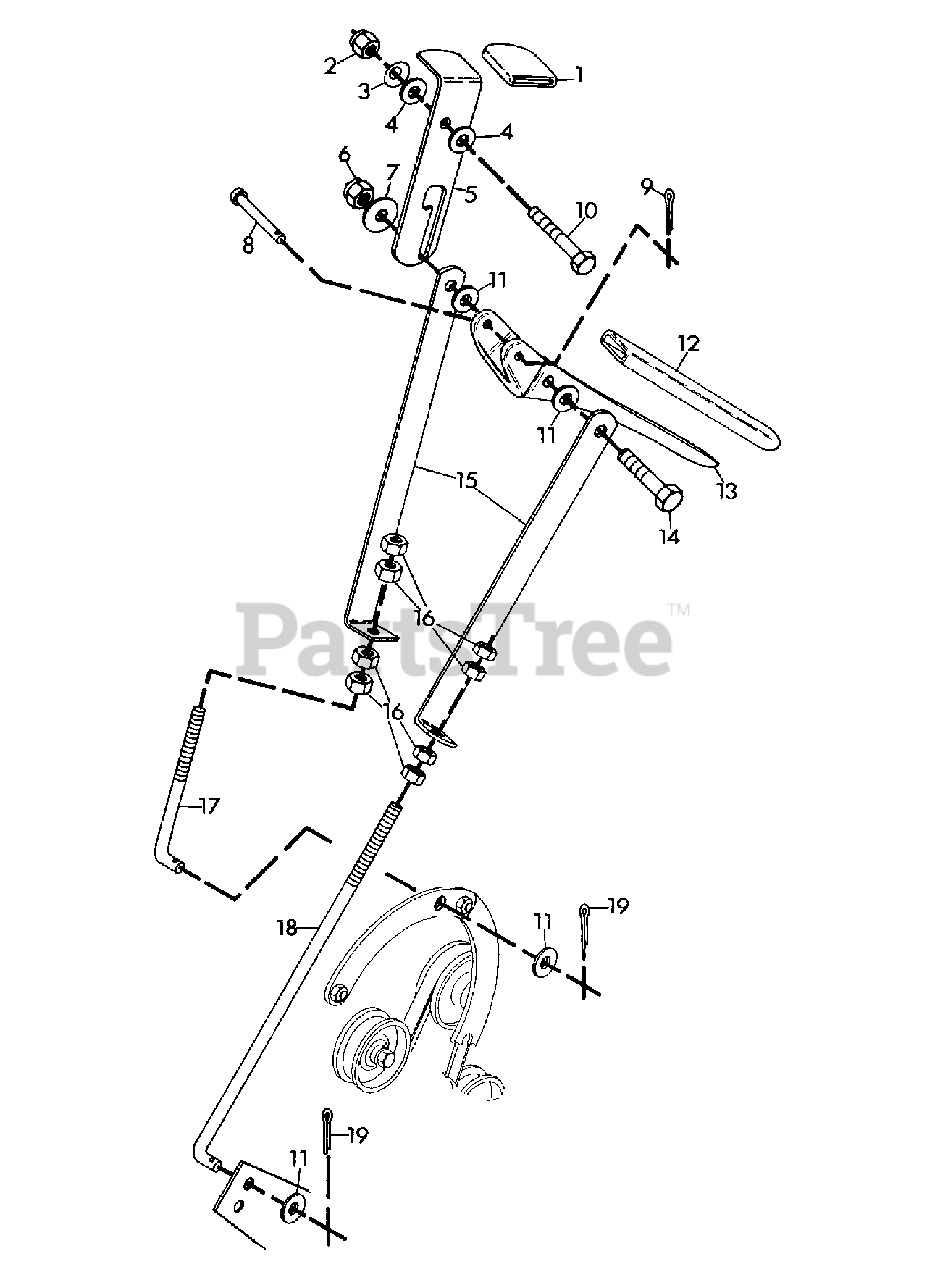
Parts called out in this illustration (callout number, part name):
1	TIP, VINYL
2	NUT, LOCK 1/4-20
3	WASHER, SPRING
4	WASHER, FRICTION
5	LEVER, CLUTCH-BRAKE LOCK
6	NUT, LOCK 5/16-18
7	WASHER, FLAT .375X1.125X.065
8	PIN, CLEVIS .187X1.70
9	PIN, COTTER .06X.50
10	BOLT, HEX 1/4-20X1.75
11	WASHER, FLAT .360X.875X.083
12	GRIP, HANDLE
13	LEVER, HAND CLUTCH
14	BOLT, HEX 5/16-18X1.50
15	STRAP, CLUTCH & BRAKE ACTUATING
16	NUT, HEX 5/16-18
17	ROD, CLUTCH
18	ROD, BRAKE LOWER
19	PIN, COTTER .09X.75
